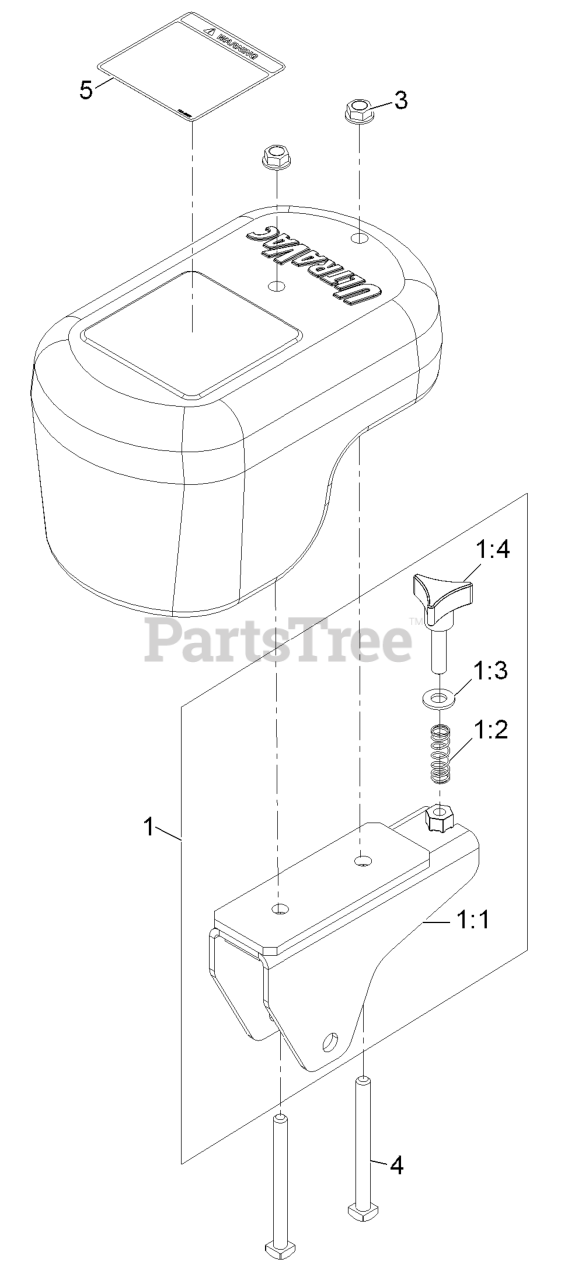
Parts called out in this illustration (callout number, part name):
1	ASM,CASTER WEIGHT BRACKET
1:1	WLD,CASTER WEIGHT BRACKET
1:3	WASHER-FLAT
3	NUT-HHF, WHIZ
4	BOLT, SQUARE HEAD YZ
5	DECAL,WEIGHT
